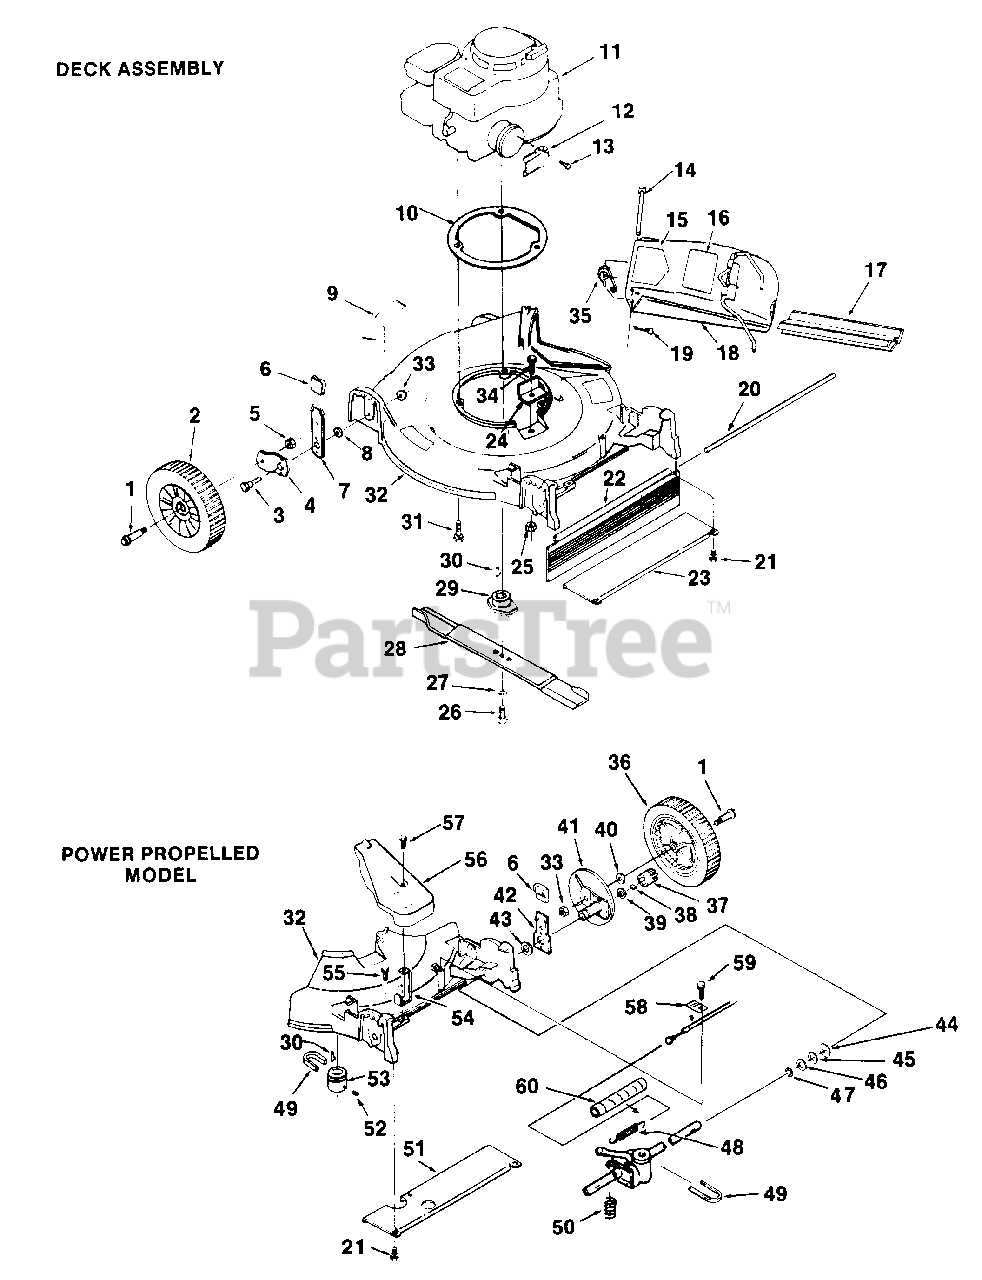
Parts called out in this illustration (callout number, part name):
1	BOLT- Axle
2	WHEEL & TIRE
3	BOLT- Hex hd.
4	ARM- Wheel adjusting
6	KNOB
7	INDEXING SPRING & PIN ASSY.
9	DECAL- Product identification
10	RING- Engine
11	ENGINE- 3.5 H.P.
12	DEFLECTOR
14	PIN- Hinge
15	LABEL- Warning
17	GUARD- Chute
18	CHUTE & LATCH ASSY.
19	PIN- Cotter
22	FLAP- Drag
23	COVER- Rear
24	COVER- Belt opening
28	BLADE
31	SCREW- Hex hd.
33	NUT- Flange
34	SCREW- Hex hd.
36	WHEEL & TIRE ASSY.
37	PINION- R.H.
38	PAWL
39	WASHER
40	WASHER
41	DRIVE WHEEL SUPPORT ASSY.
42	INDEXING SPRING & PIN ASSY.
43	SPACER
44	WASHER
45	WASHER
46	WASHER- (Shim)
47	RING- Eaton
48	SPRING- Extension
49	BELT- Drive
50	SPRING- Compression
51	COVER- Rear
52	SCREW
53	PULLEY- Drive
54	BRACKET- Gear box cover
55	SCREW
56	COVER- Drive
57	SCREW- 1/4-20 x 3/4
58	CLAMP- Cable
59	SCREW- 1/4-20
60	COVER- Spring
